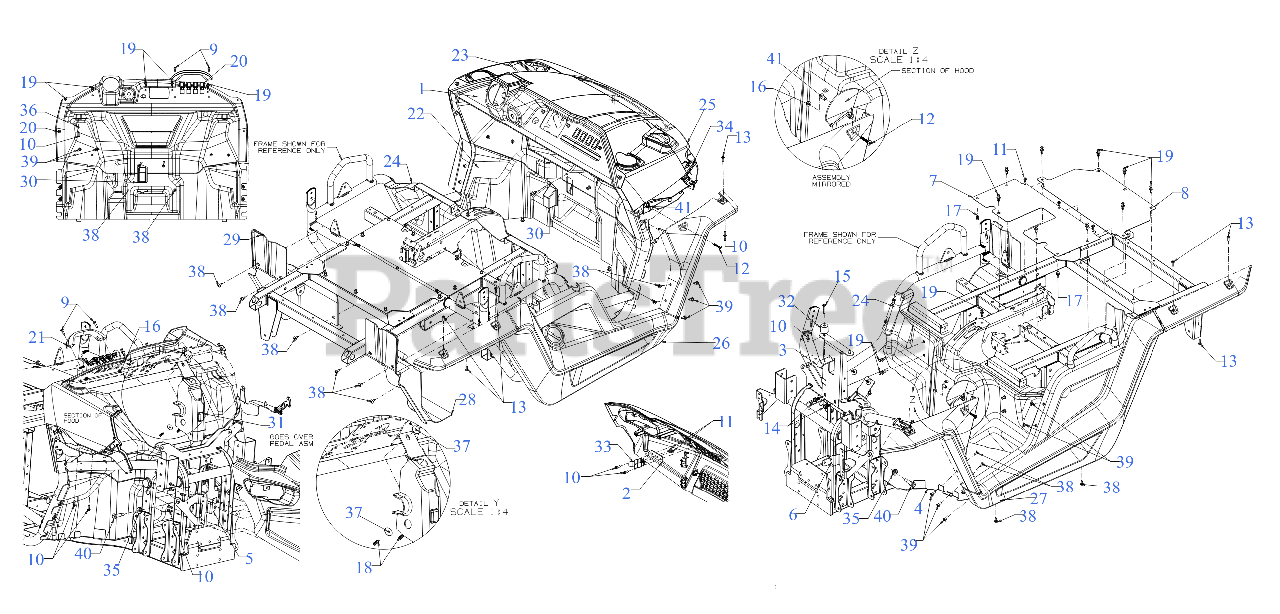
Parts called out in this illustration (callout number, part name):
1	UPPER DASH ASSEMBLY
2	GRILLE MOUNTING BRACKET
3	HOOD FRAME SUPPORT BRACKET
5	GRILLE PIVOT BRACKET (RH)
6	GRILLE PIVOT BRACKET (LH)
9	SCREW 1/4-20 x 1.0
10	SCREW 1/4 x .750
11	SCREW 1/4-20 X.500
12	SCREW 1/4-20 x 1.50
13	SCREW-1/4-15 x 0.750 PHILLIPS
14	SCREW 3/8-16 x 3/4
15	SCREW 1/4-20 X1.625
16	FLANGE LOCK NUT
17	RUBBER PLUG
18	RATCHET CLIP
19	PLASTIC RIVET
20	PANEL SWITCH PLUG
21	GRAB HANDLE
22	UPPER FLOOR BOARD COVER
23	FRONT HOOD
24	FRONT SEAT COVER
25	PIVOT HOOD
26	MIDDLE FENDER (RH)
27	MIDDLE FENDER (LH)
28	INNER FENDER (RH)
29	INNER FENDER (LH)
30	THROTTLE CABLE COVER
31	THROTTLE PEDAL COVER
32	HOOD LATCH ROLLER
33	HOOD LATCH SPRING
34	HOOD STRAP
35	GROMMET .500 x 1.00 x .281 LTV
36	FLAT WASHER
37	FLAT WASHER
38	TORX SHOULDER SCREW 1/4-20
39	SHOULDER SCREW .375X.280:1/4-14
40	SHOULDER SCREW .496X1.44 3/8-16
41	SHOULDER SPACER
